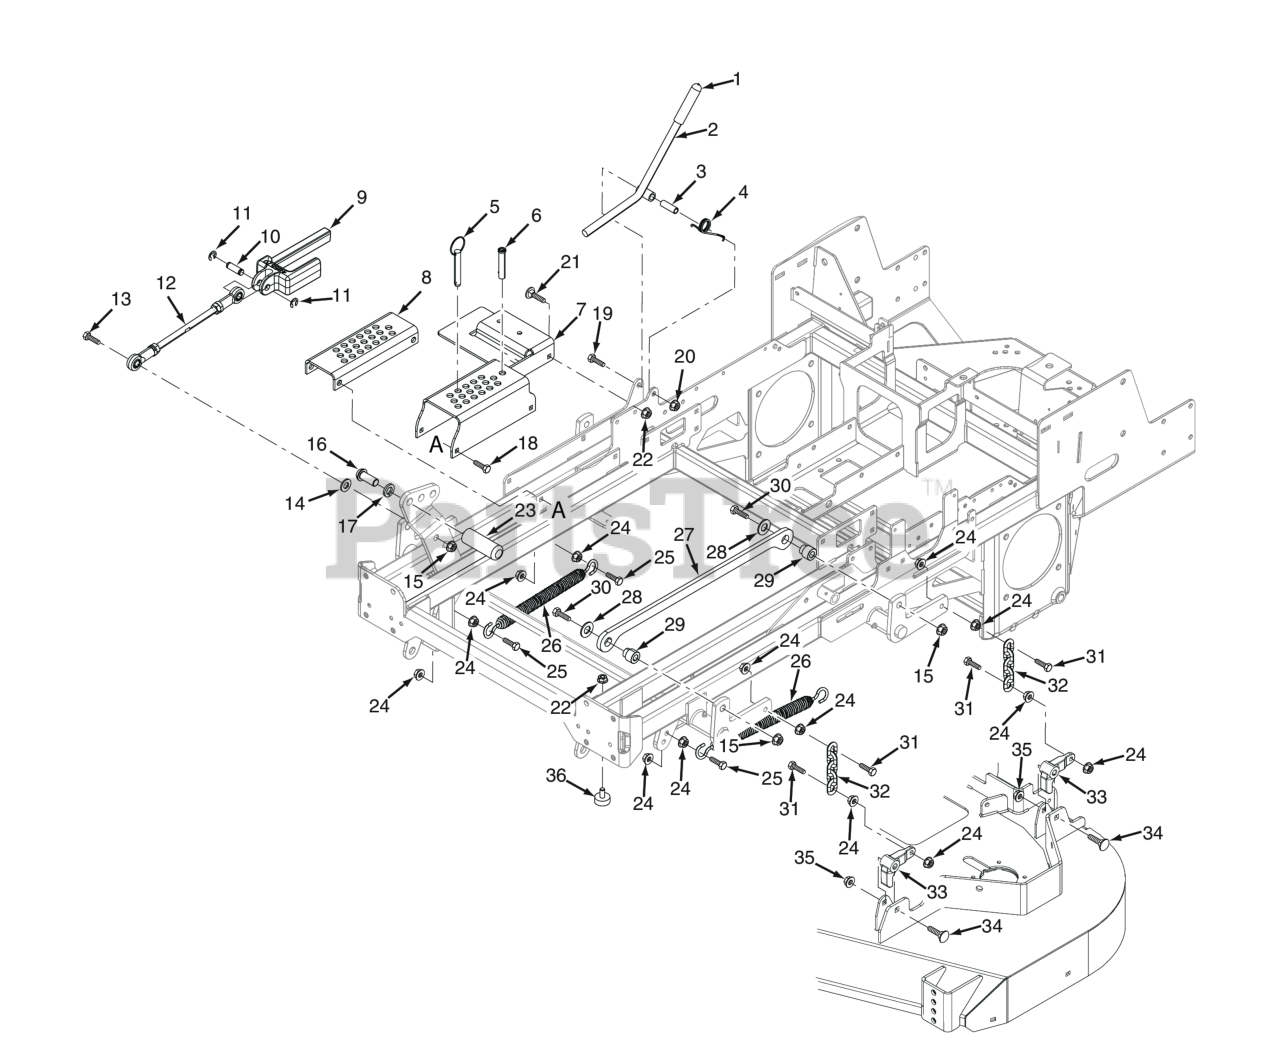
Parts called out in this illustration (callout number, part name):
1	Mounting Bracket, Fuel Tank
2	Deck Latch Assembly w/Grip
3	Bushing, .502 O.D.
4	Spring, Torsion - Lever Return
5	Lanyard, Deck Height Pin Assembly
6	Pin, Locking
7	Adjustment Bracket, Upper Cut Height
8	Adjustment Bracket, Lower Cut Height
9	Slide, Height Adjustment Assembly (INCL. 10,11,12)
10	Pin, Deck Lift
11	Retaining Ring, 1/2" Ext. "E"
12	Linkage, Deck Lift
13	Hex Head Bolt, 1/2-13 x 2"
14	Flatwasher, 1/2 - .531 x 1.062 x .095
15	HEX LOCKNUT, ELASTIC STOP, 1/2-13
16	Capscrew, 5/8-11 x 1-1/2"
17	Lockwasher, 5/8" Spring
18	Bolt, Hex Wshr Head 5/16-18 x 1-1/4"
19	Capscrew, Hex Head 3/8-16 x 2.75"
20	HEX NUT, ELASTIC STOP LOCK, 3/8-16
21	Bolt, 5/16-18 x .75 RHSN Carriage
22	Nut, Serrated Flange 5/16-18 (Right Front Engine Mounting, Briggs and Kohler Only)
23	Foot Pedal, Height Adjustment
24	NUT, 3/8-16 SERRATED FLANGE HEX HEAD
25	Bolt, Hex Head 3/8-16 x 1-1/2" Grade 8 Black
26	Spring, Helper (61" & 72" Cutter Decks Only)
27	Link, Deck Lift
28	Flat Washer, 1/2 (.562 x 1.375 x .109)
29	Pivot, Deck Link
30	Bolt, Hex Head 1/2-13 x 2-1/4"
31	Bolt, Hex Head 3/8-16 x 1-1/2" B&S 32BV
32	Chain, Deck Lift
33	Lever, Deck Level
34	Bolt, Carriage 7/16-14 x 2-1/4"
35	HEX LOCKNUT, ELASTIC STOP, 7/16-14
36	Bumper, Rubber 5/16-18 x 5/8"
